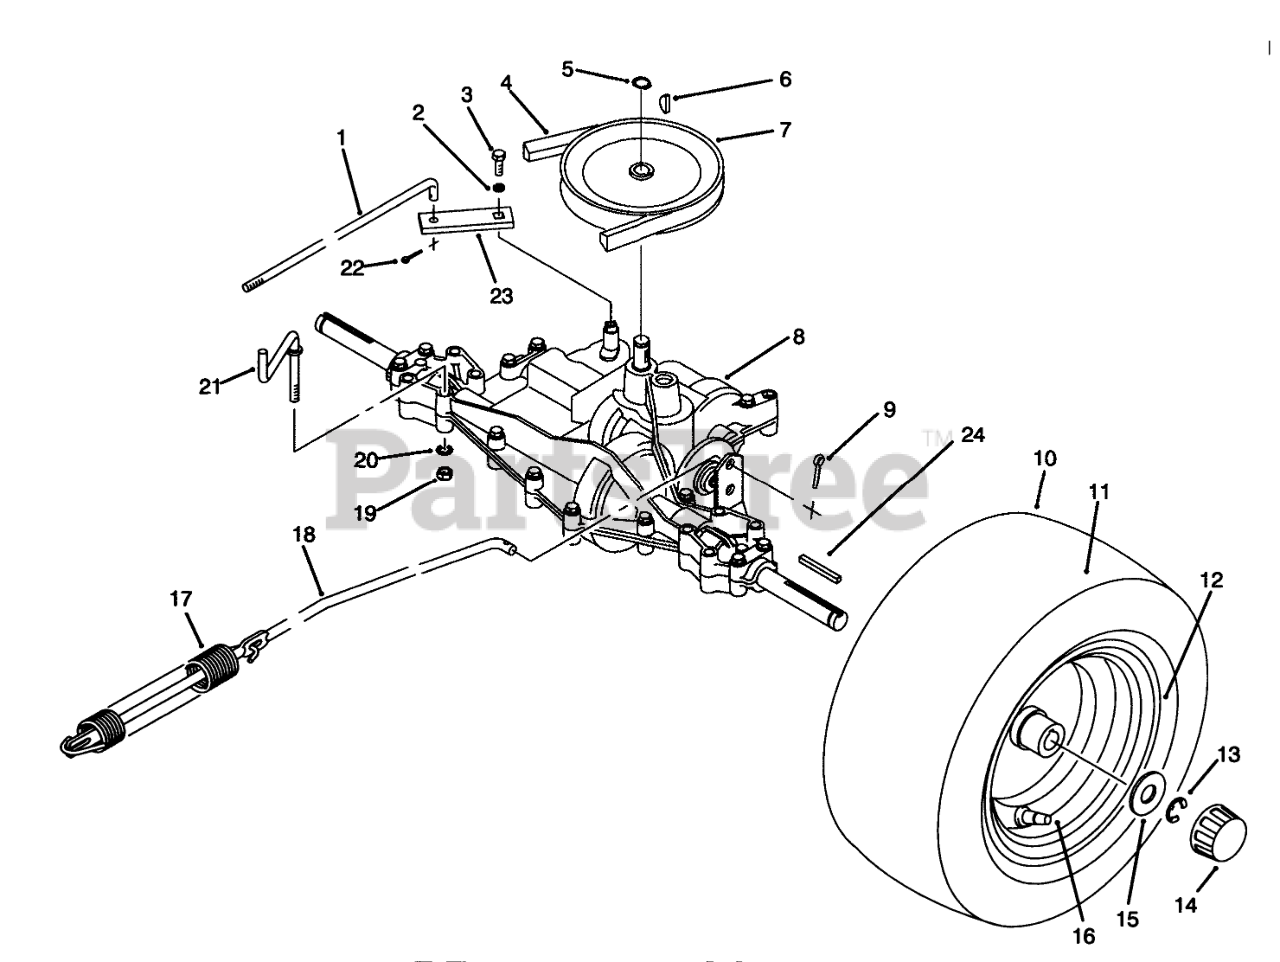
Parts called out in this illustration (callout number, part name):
1	LINK-SHIFT
2	WASHER-LOCK
3	SCREW-HH
4	V-BELT, TRACTION
5	RING-SNAP, EXTERNAL
6	KEY-WOODRUFF
7	PULLEY-TRANSAXLE
8	TRANSAXLE 915-019
9	PIN-COTTER
11	TUBE-INNER
12	REAR WHEEL ASM
13	E-RING
14	CAP-HUB
15	WASHER-PLAIN
16	STEM-VALVE
17	SPRING-EXT
18	ROD-BRAKE
19	NUT-LOCK, NI
20	WASHER-LOCK, INTERNAL
21	GUIDE-LOWER BELT
22	PIN-COTTER
23	LINKAGE
24	KEY-SQUARE
